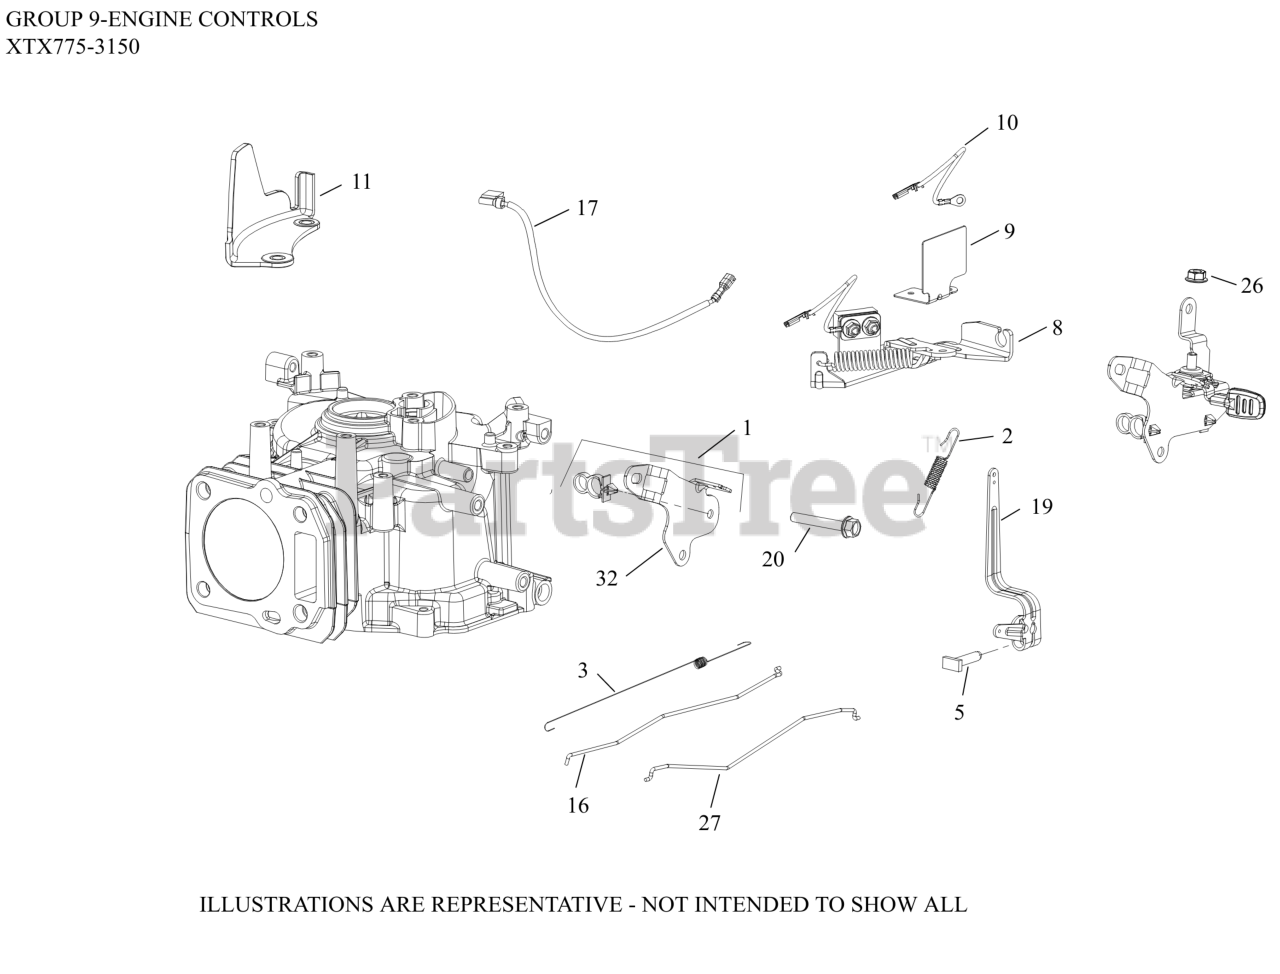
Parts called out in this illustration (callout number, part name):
1	BRACKET ASSEMBLY, FIXED SPEED CONTROL
2	SPRING, EXTENSION (GOVERNOR)
3	SPRING, LINKAGE
5	SCREW, RECTANGLE HEAD (M6)
8	BRAKE ASSEMBLY
9	GUARD, BRAKE - USE 14 314 30-S
10	LEAD, KILL (BRAKE TO IGN. MODULE)
11	GUARD, FINGER
16	LINKAGE, GOVERNOR - USE 14 079 30-S
19	LEVER, GOVERNOR
20	SCREW, HEX FLANGE (M6)
26	NUT, HEX FLANGE LOCK (M6)
27	LINKAGE, CHOKE
32	BRACKET, FIXED SPPED - DISCONTINUED
